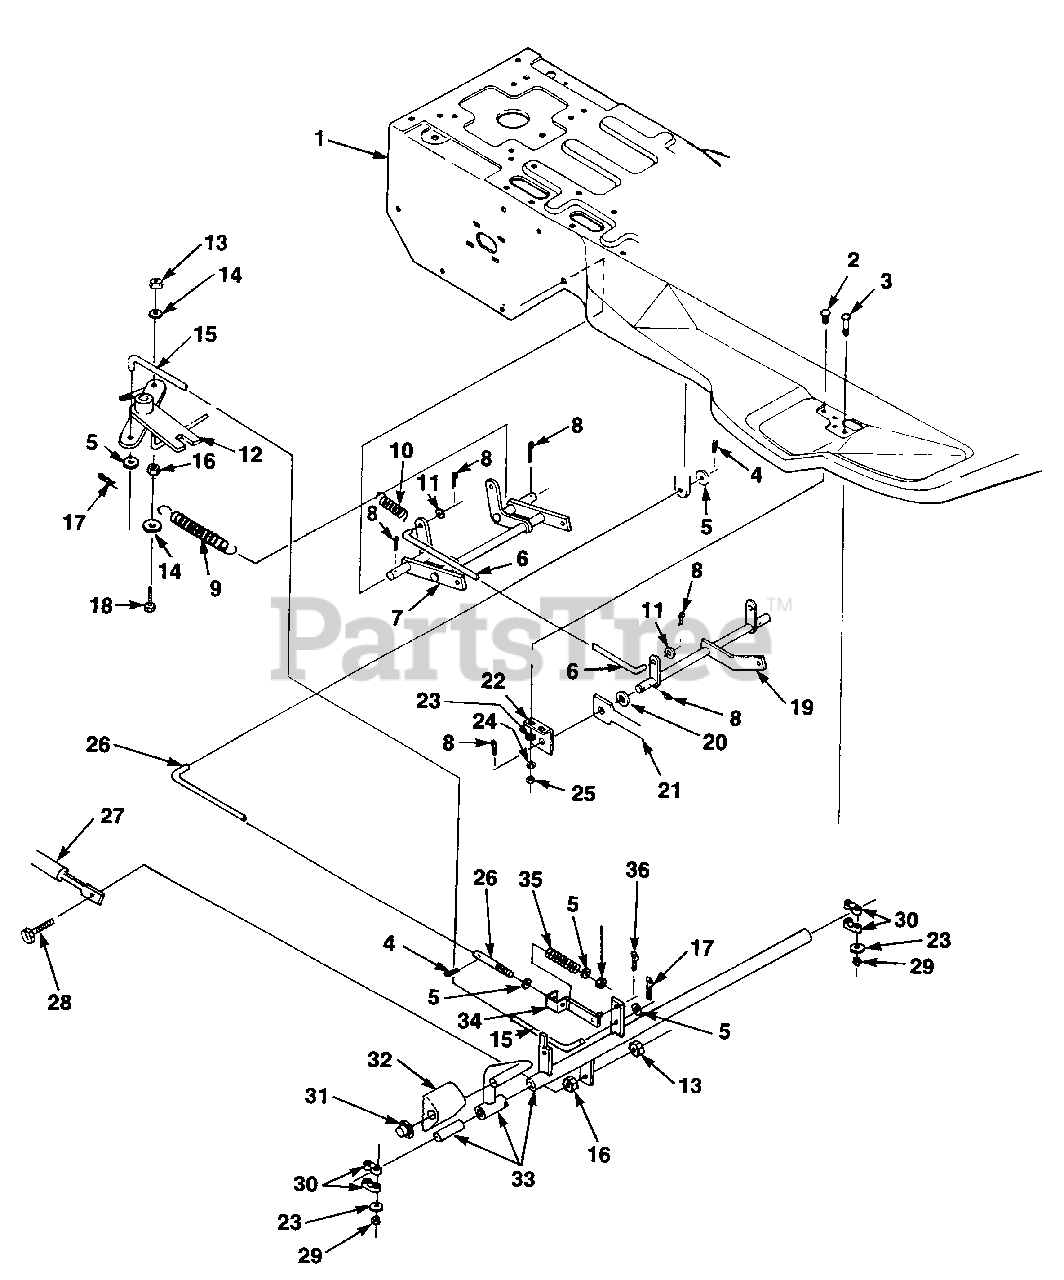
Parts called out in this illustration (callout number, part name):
3	BOLT- 1/4-20 x 1 1/2
4	PIN- Cotter
5	Superseded by UP07173
6	ROD- Deck lift
11	Superseded by PS84010
16	Superseded by 81018
17	PIN- Cotter 1/8 x 3/4
18	Superseded by UP03452
21	SUPPORT- Front axle
23	Superseded by 84026
25	Superseded by JA993730
28	SCREW- (5/16-18 x 1 1/2")
29	Nut - hex 1/4-20 lock
31	NUT- Push
32	PEDAL- Rubber
34	BRACKET- Brake Spring
35	SPRING- Comp Brake
36	PIN- Cotter
